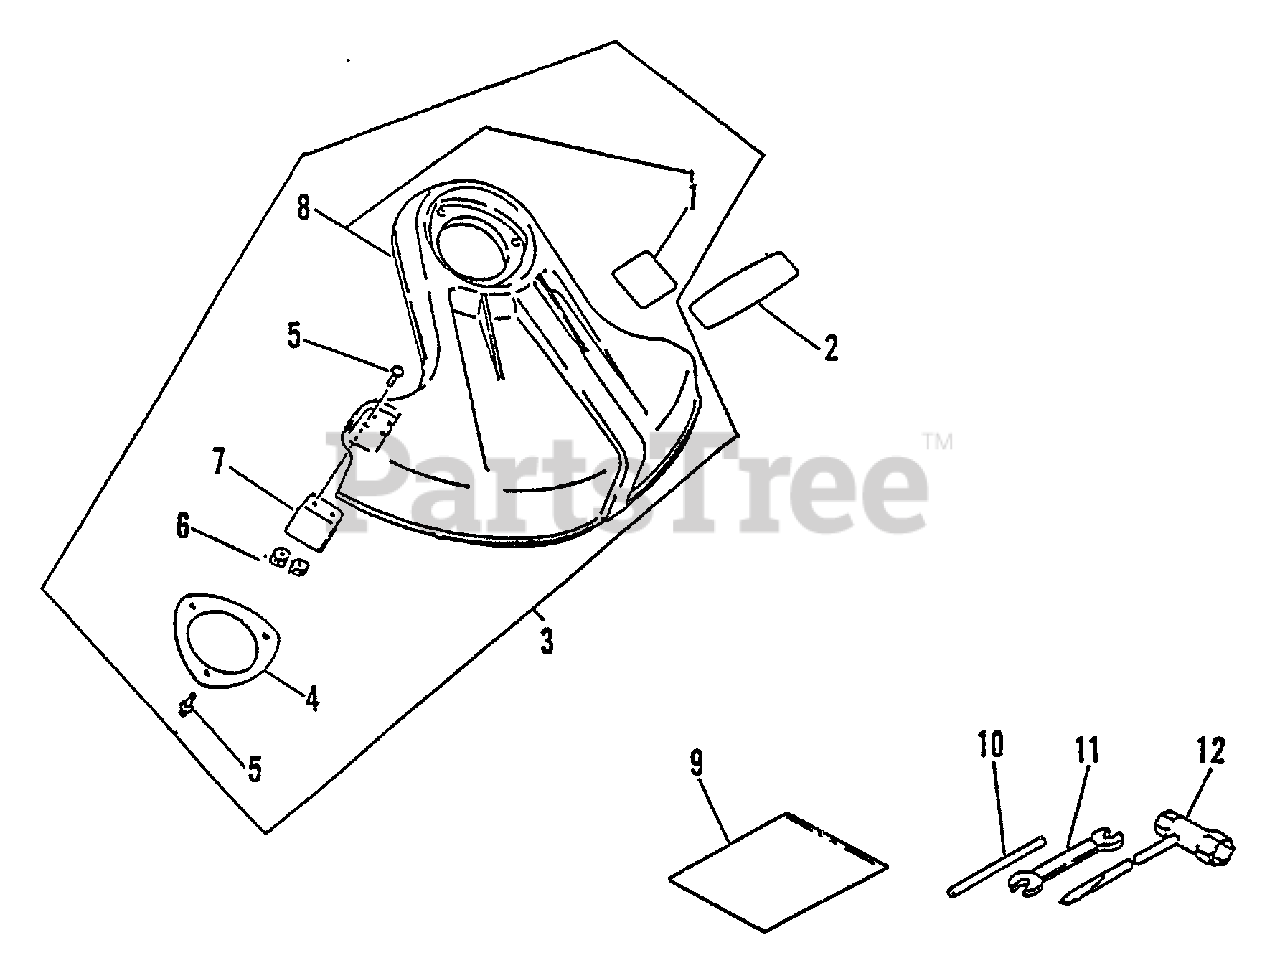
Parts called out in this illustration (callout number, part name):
1	LABEL - CAUTION
2	LABEL
3	SHIELD ASSY
4	PLATE, SHIELD Ø49.5 MM
5	SCREW 5×16
6	NUT M5
7	CUTTER, LINE
8	SHIELD, DEBRIS
9	BAG, TOOL
10	TOOL, LOCKING 5×120 MM
11	SPANNER 8×10
12	T-WRENCH 17x-19 L200
